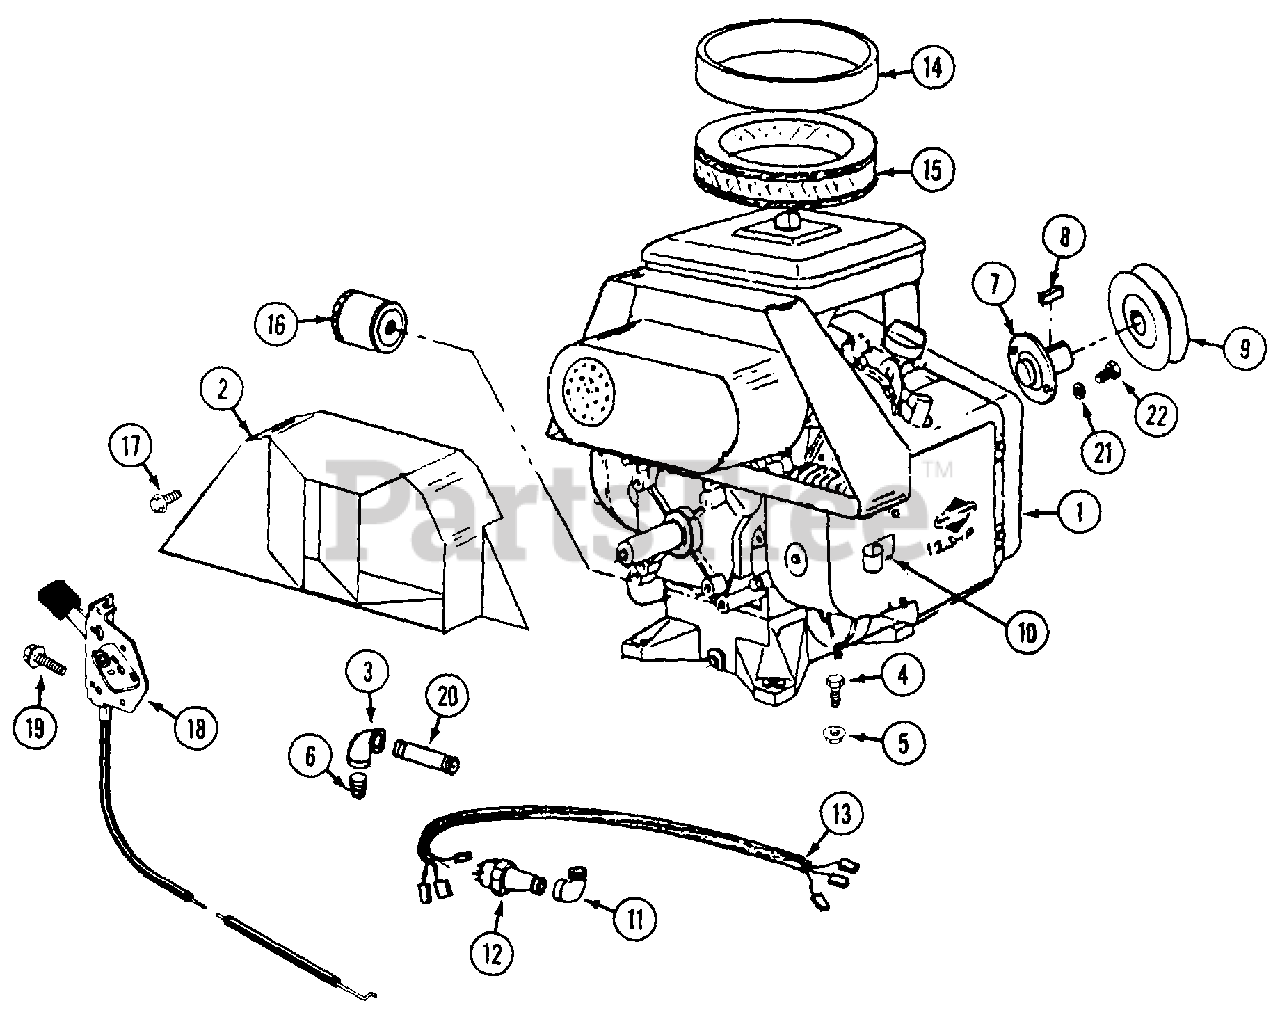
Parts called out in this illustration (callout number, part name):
1	ENGINE - Briggs and Stratton
3	ELBOW - 3/8"
4	BOLT - 5/16"-18 x 1-1/4"
5	NUT - 5/16"-18
6	PLUG - pipe 3/8"
8	KEY - 1/4" x 1/4" x 1"
9	PULLEY - drive
10	RETAINER - starter cable
11	ELBOW - street 1/8"
12	UNIT - oil sending
13	HARNESS - wire
14	PRECLEANER
15	FILTER - air
16	FILTER - oil
17	BOLT - 1/4"-20 flange lock
18	CABLE - throttle
19	SCREW - #12 x 1/2"
20	NIPPLE - 3/8"
21	LOCKWASHER
22	BOLT - 3/8"-16 x 1"
